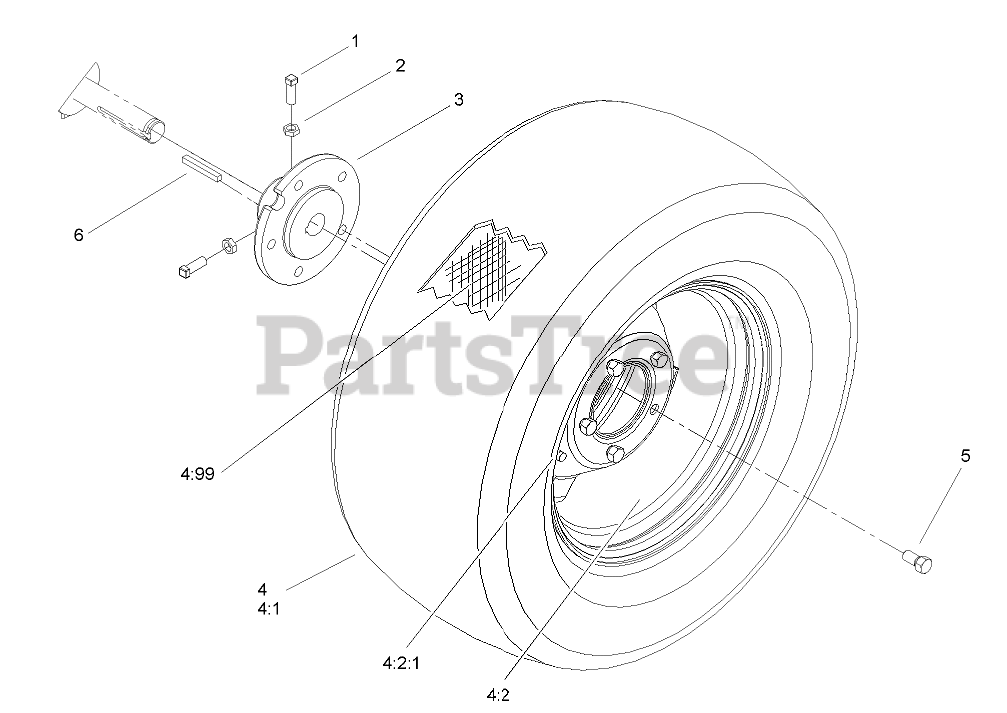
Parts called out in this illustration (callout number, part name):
1	SCREW-SET, SQH
2	NUT-JAM
3	HUB-WHEEL
4	Wheel and Tire ASM-Rear
4:2	WHEEL
4:2:1	VALVE
4:99	TUBE-INNER
5	BOLT-LUG
6	KEY-SQUARE
